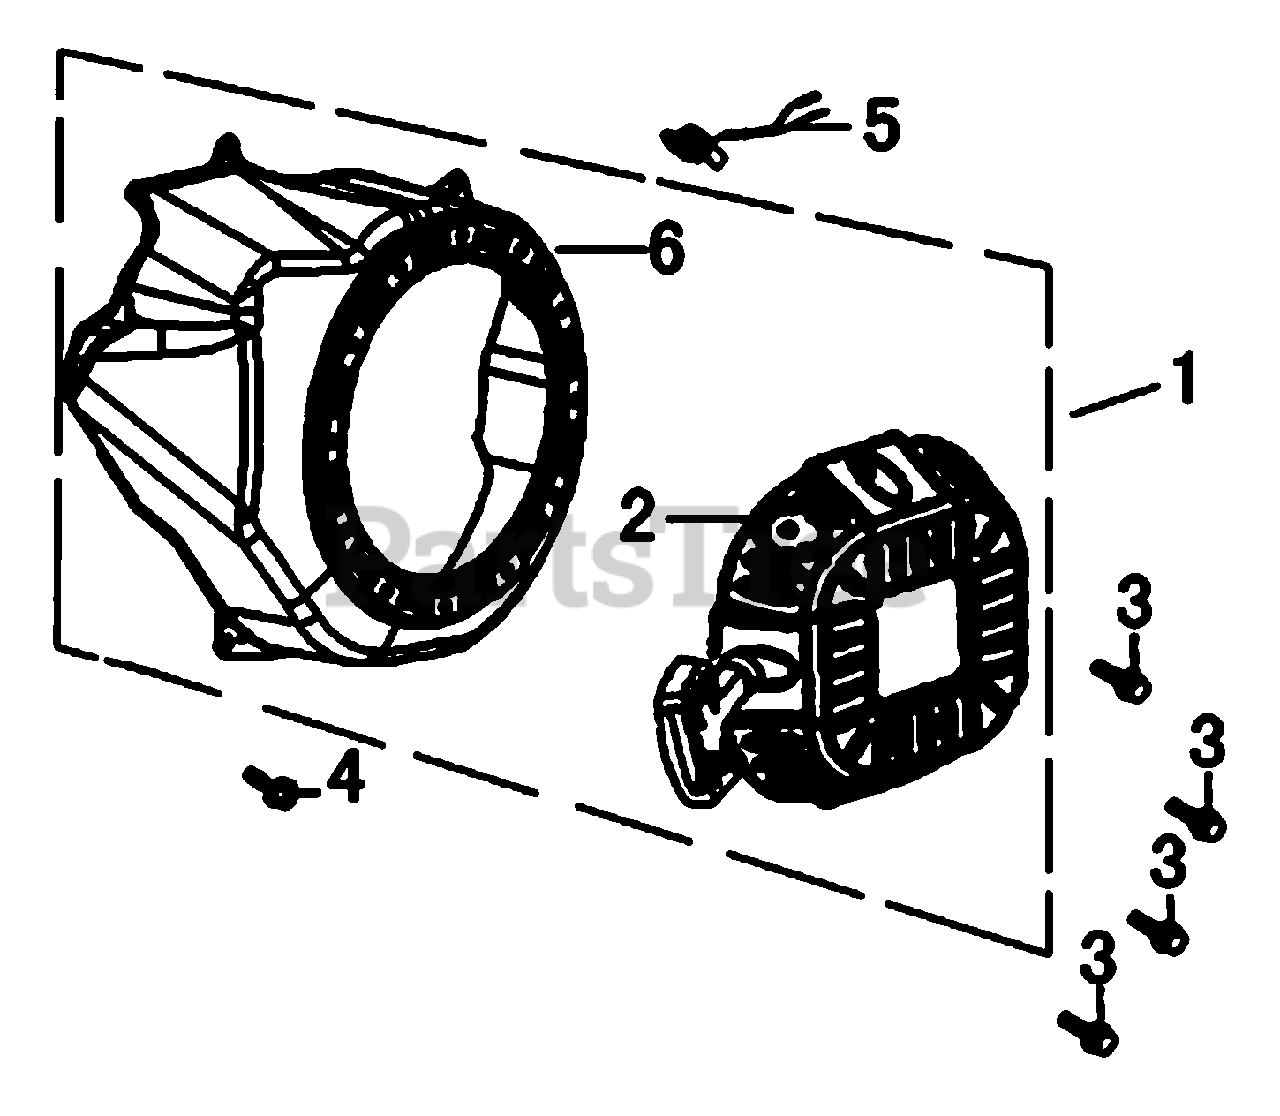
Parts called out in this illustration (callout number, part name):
1	RECOIL STARTER COMP.
2	RECOIL COVER ASSY-G200F
3	BOLT, FLANGE 6X8
4	BOLT, FLANGE 6X10
5	SWITCH, ON/OFF RED-ROTARY
6	BLOWER HOUSING/SHROUD
